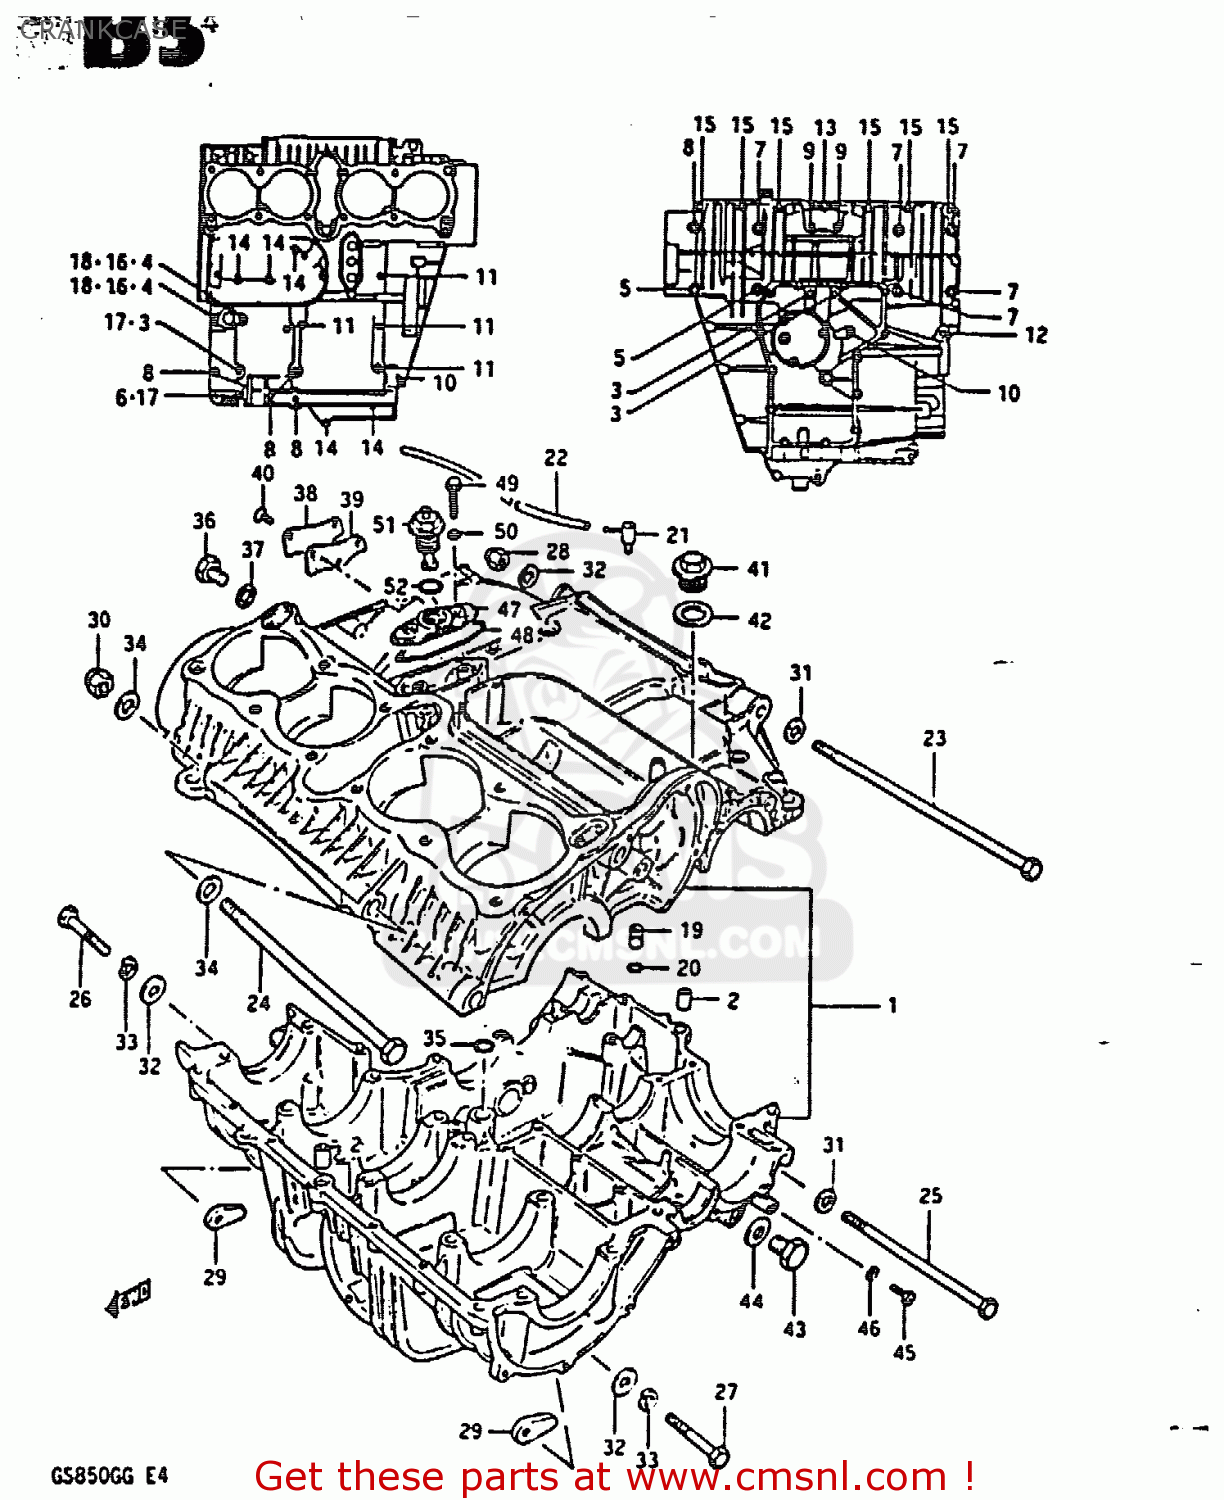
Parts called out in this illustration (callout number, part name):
1	CRANKCASE SET
2	PIN
3	BOLT
4	BOLT 8X110
5	BOLT
6	BOLT
7	BOLT (8X90)
8	BOLT (8X65)
9	BOLT 8X60
10	BOLT (6X90)
11	BOLT (6X75)
12	BOLT 6X55
13	BOLT 6X50
14	BOLT (6X45)
15	BOLT 6X35
16	NUT
17	NUT 8MM
18	GASKET 8.2X14X1 (NAS)
19	UNION
20	O RING(D:1.05,ID:3.1)
21	BPLUG,BEVEL GEAR BREATHER
22	HOSE
23	BOLT
24	SHAFT,REAR SWING ARM
25	BOLT
26	BOLT (10X60)
27	BOLT (10X50)
28	NUT (10MM)
29	NUT
30	NUT
31	WASHER (10.5X20X3.2)
32	WASHER
33	LOCK WASHER
34	WASHER
35	O RING(D:3.2,ID:12.9)
36	PLUG (14X12)
37	GASKET(14X19.2X2) (NAS)
38	CAP,OIL GALLERY
39	GASKET,OIL GALLERY (MCA)
40	SCREW
41	PLUG
42	GASKET
43	PLUG
44	GASKET(14X19.2X2) (NAS)
45	SCREW(6X10)
46	WASHER
47	HOUSING,OIL PRESSURE SWITCH
48	O RING,PRESSURE SWITCH HOUSING
49	BOLT
50	WASHER
51	SWITCH ASSEMBLY
52	O RING(D:1.9,ID:18.8)
